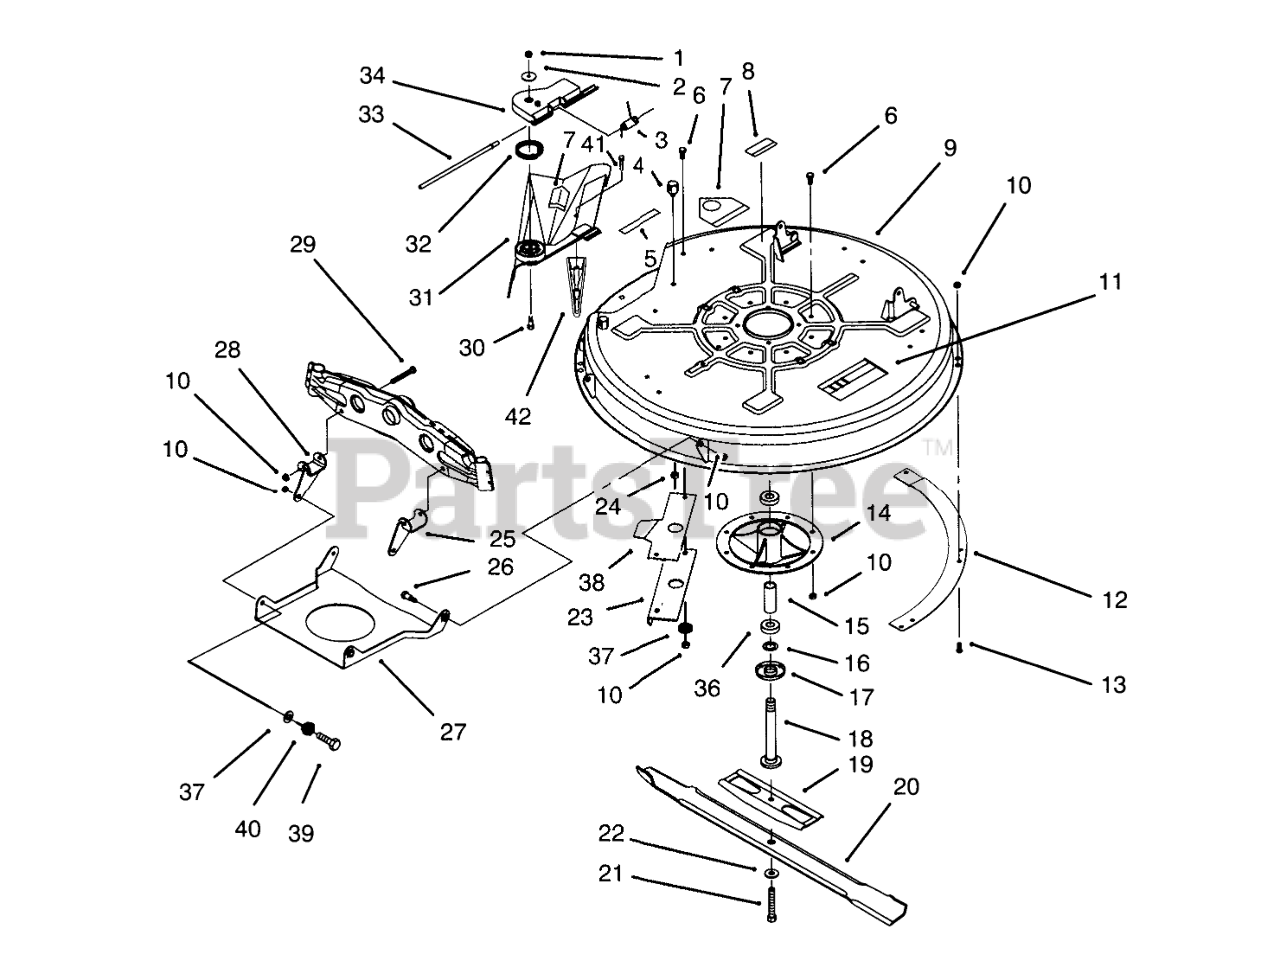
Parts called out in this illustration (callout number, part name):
1	NUT-LOCK, NI
2	WASHER-FLAT
3	SPRING-TORSION
4	POST-PIVOT
5	DECAL-DANGER, DEFLECTOR
6	SCREW-HH
7	DECAL-DANGER
8	DECAL-WARNING
9	Cutter Deck-32"
10	NUT-LOCK, NI
11	DECAL-DANGER, THROWN OBJECT
12	Ring-Wet Grass (Model No. 71200 Only)
13	SCREW-PPH
14	SPINDLE
15	SPACER-BEARING
16	SPACER-HARDNED
17	SHIELD-BEARING
18	SHAFT-SPINDLE
19	STIFFENER
20	Blade
21	SCREW-HH
22	WASHER-BELLEVILLE
23	Baffle Deck
24	NUT-LOCK, NI
25	Bracket-L.H.
26	BOLT-SHOULDER
27	Pan-Front Deck Susp.
28	Bracket-R.H.
29	SCREW-HH
30	BOLT-SHOULDER
31	Deflector Assembly(Incl. Ref. #7)
32	SPRING-TORSION
33	ROD-HINGE, DEFLECTOR
34	PIVOT-HINGE, DEFLECTOR
36	BEARING-BALL
37	WASHER-PLAIN
38	Ramp-Deflector
39	SCREW-HH
41	SCREW-PPH
42	KICKER
